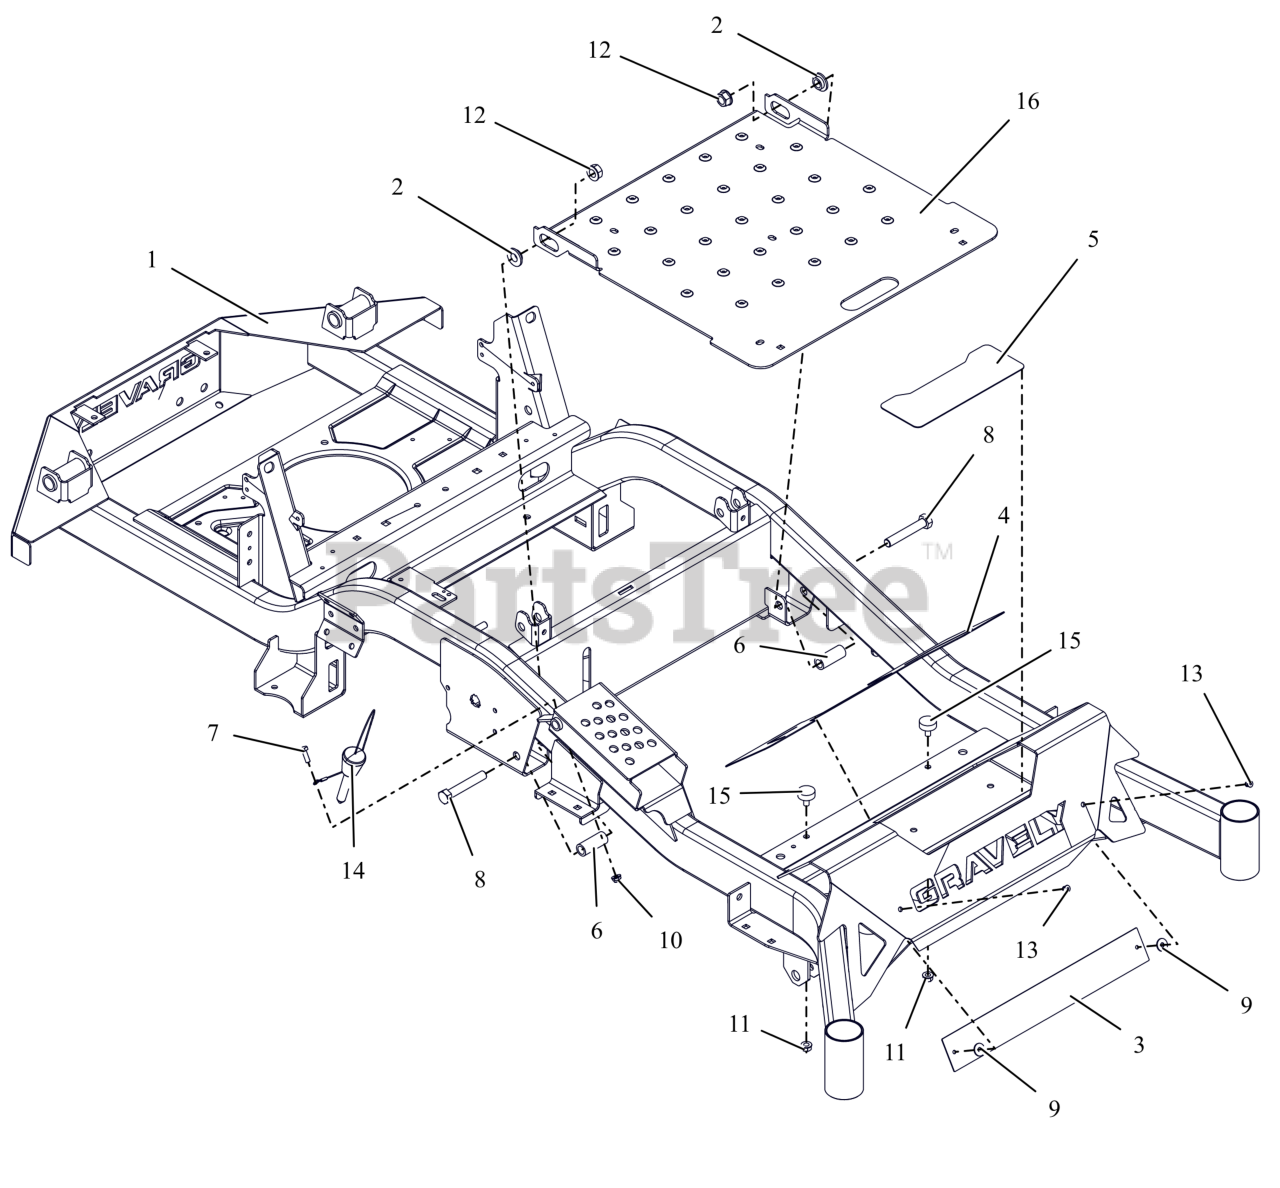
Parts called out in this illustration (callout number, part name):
1	WLDMT, MAIN FRAME -HD 44/52
2	BSHG-FLG .515X.750X.310X1.120
3	PLATE, BACK FOOT-REST XL
4	GRIP, FRONT
5	GRIP, STEP
6	SPACER, .515X.75X1.83
7	BLT, HEX .25-20X.75 G5 ZCC
8	BLT, HEX .50-13X3.00 G5 ZCC
9	WSHR, RBR W/ADHESIVE .25X.75X.06
10	NUT,NYL-FLG .25-20 GF ZCC
11	NUT,SPNLK-FLG .31-18 G5 ZCC
12	NUT-LK-TOP-FLG .500-13 GF ZCC
13	RIVET, .1875 AL/AL .126-.250
14	PIN- MAGNETIC .50X2.70
15	BUMPER, RUBBER
16	KIT,ACCESS PANEL W/DECALS-RED
